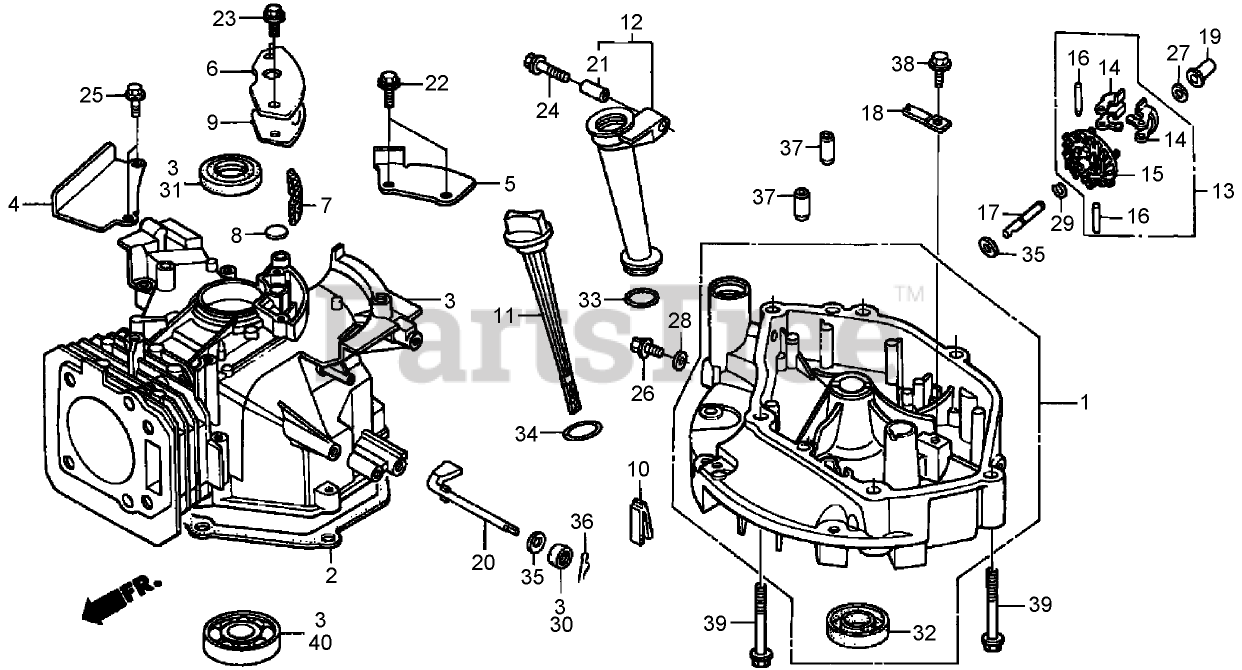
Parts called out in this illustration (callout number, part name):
1	OIL PAN ASM
2	GASKET-PAN, OIL
3	CYLINDER ASM
4	Plate-Guide
5	Plate A-Guide
6	COVER-BREATHER
7	Filter-Breather
8	VALVE-BREATHER
9	GASKET-COVER, BREATHER
10	RUBBER-RETURN, OIL
11	Dipstick-Oil
12	EXTENSION-FILLER, OIL (106 mm)
13	GOVERNOR ASM
14	Weight-Governor
15	HOLDER-WEIGHT, GOVERNOR
16	PIN-WEIGHT, GOVERNOR
17	SHAFT-HOLDER, GOVERNOR
18	Plate-HOLDER, Governor Shaft
19	SLIDER-GOVERNOR
20	SHAFT-ARM, GOVERNOR
21	Collar-Extension
22	BOLT-FLANGE (6X12) (C T200)
23	BOLT-FLANGE (6X14) (C T200)
24	Bolt-Flange (6X32)
25	BOLT-FLANGE (6X20) (C T200) (engine serial numbers up to 6702082)
26	Bolt-PLUG, Drain
27	WASHER-THRUST(6MM)
28	WASHER-PLUG, DRAIN (102MM)
29	CLIP-HOLDER, GOVERNOR
30	SEAL-OIL (6X11X4)
31	SEAL-OIL (25X38X7)
32	SEAL-OIL (25.4X40X7)
33	O-Ring (22.5X2.2)
34	O-Ring (26X2.7)
35	WASHER-PLAIN (6MM)
36	PIN-LOCK (8MM)
37	Pin-Dowel (8X14)
38	Bolt-Flange (6X12)
39	BOLT-FLANGE (8X50)
40	BEARING-BALL, RADIAL (6205)
